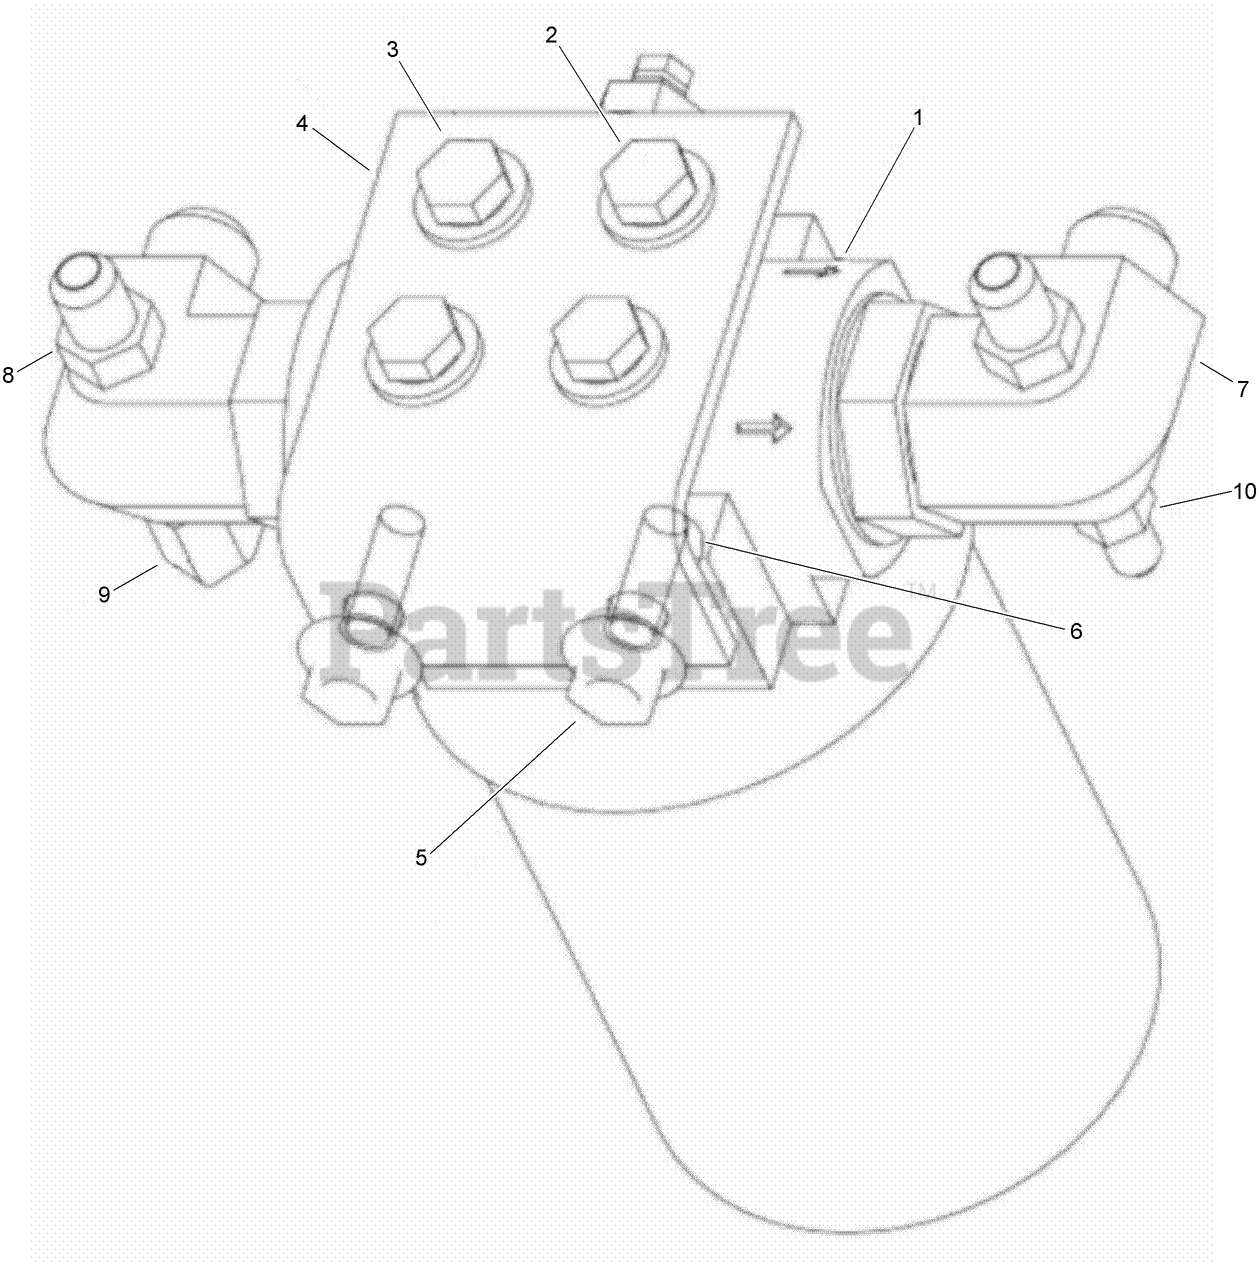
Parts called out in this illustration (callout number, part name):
1	OIL FILTER ASM
2	WASHER-FLAT
3	SCREW-HH
4	BRACKET-MOUNTING, FILTER
5	SCREW-HH
6	NUT-FLANGE, NYLOCK
7	ADAPTER-SPECIAL
8	CONNECTOR-37FL 3/8 Tube x 1/8 NPTF
9	ELBOW-90
10	CONNECTOR-37FL 1/4 Tube x 1/8 NPTF
